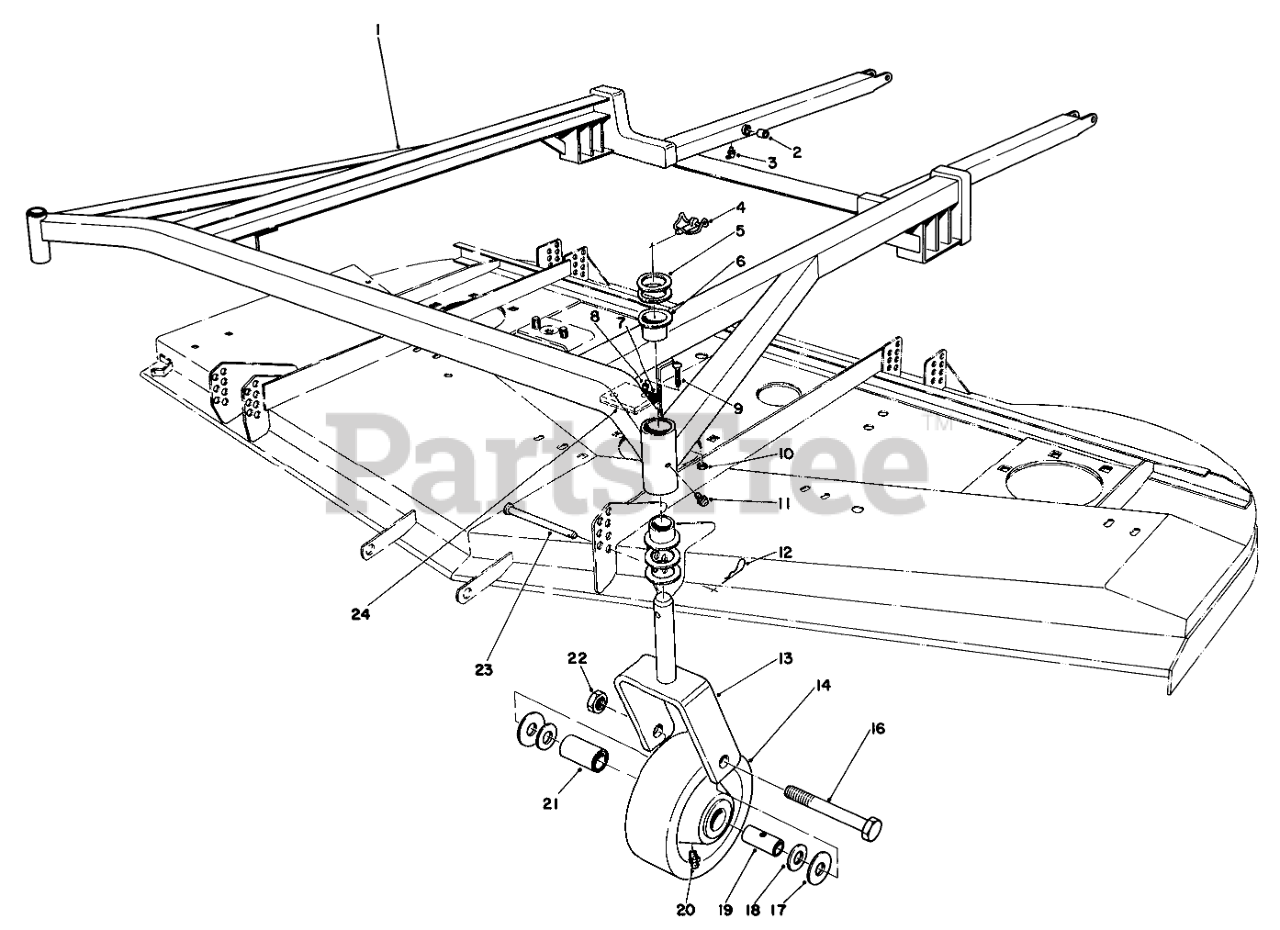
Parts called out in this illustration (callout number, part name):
1	Frame (Incl. Ref. #2, 3 & 6)
2	7/8 ID X 1.128 X 7/8 LG BSHG
3	FITTING-GREASE, 90 DEG
4	PIN-LYNCH
5	WASHER-THRUST
6	Bushing
7	CUSHION-RUBBER
8	SPACER
10	NUT-LOCK, NI
11	FITTING-GREASE
12	PIN-HAIR
13	FORK-Castor
14	Castor Wheel (Incl. Ref. #17-21)
16	SCREW-HH
17	THRUST WASHER
18	BEARING RETAINER
19	SPANNER BUSHING
20	FITTING-GREASE
21	ROLLER BEARING
22	NUT-LOCK
23	PIN-CLEVIS
24	SHIM-CUSHION
